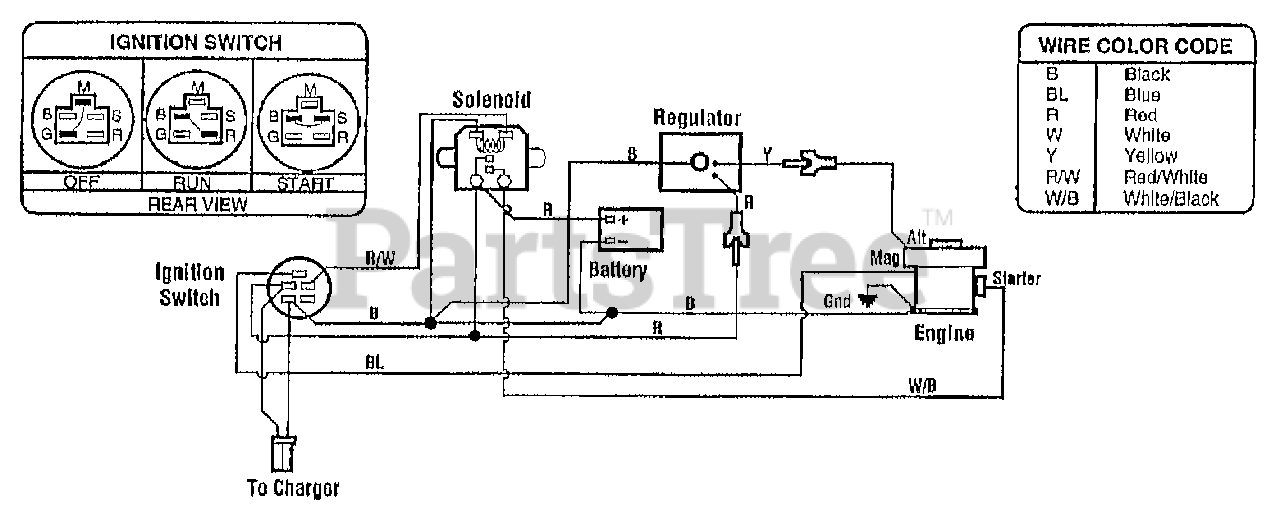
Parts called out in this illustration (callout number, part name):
1	STARTER-ELEC B&S
3	ASSM-KEYSWITCH
4	NUT-HEX/JAM 3/8-16
5	TIE-CABLE NYLON BLACK
6	NUT-HEX 1/4-20 ZP
9	CHARGER-BATTERY
10	BOOT-CABLE
11	SCR-HFLK
12	CLIP-J
13	SOLENOID
14	BRKT-BATTERY
15	ADAPTER-HARNESS
16	ASSM-WIRE LEAD
17	HARNESS-WIRING
18	ADAPTOR-CHARGER LEAD
19	REGULATOR (B&S)
20	SPACER
21	PAD-BATTERY
23	SCR 1/4-20X.5 FL SELF TAP
24	SCR-HFLK 5/16-18X.75 ZP
25	WASHER-FLAT 5/16 SAE
